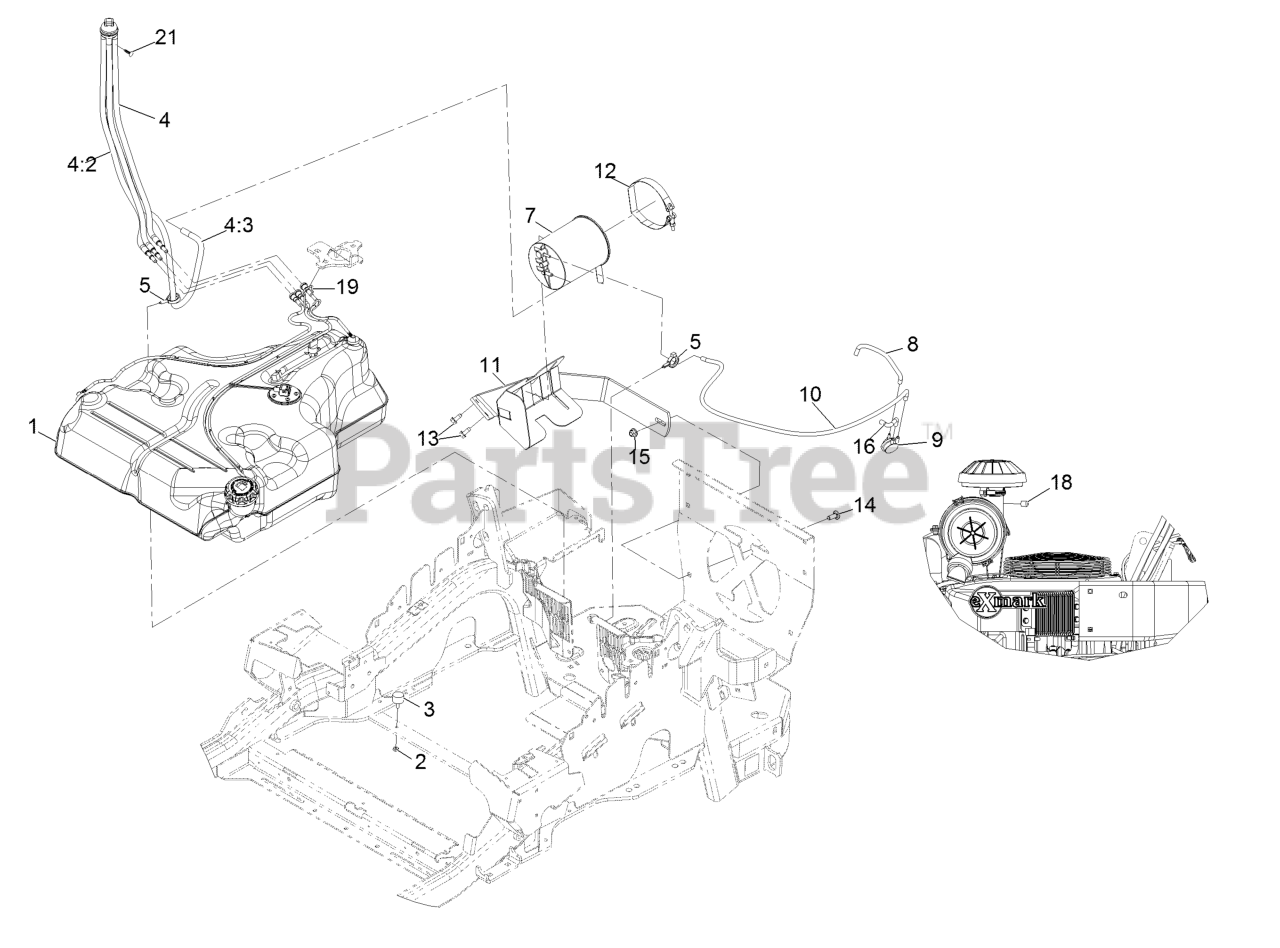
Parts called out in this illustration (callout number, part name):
1	ASM-8 Gallon Fuel Tank
2	Nut-Jam 1/4-20
4	Fuel Manifold Vent ASM
4:2	Hose-Fuel Line 24"
4:3	Hose-Fuel
5	Clamp-Hose
7	Canister-Carbon, 1200Cc
8	Hose-Vent,Formed
9	Valve-Control, Vacuum
10	Hose,Vent,Formed
11	Mount-Canister
12	Clamp, T-Bolt
13	Screw-HWH 5/16-18 X 3/4 Tf
14	Bolt-Carriage 3/8-16 X 1
15	Nut-Nyloc 3/8-16 Flg
16	Hose-Vent, Formed
18	Plug-Port
19	Retainer-Line, Vapor
21	Plug-Plastic
